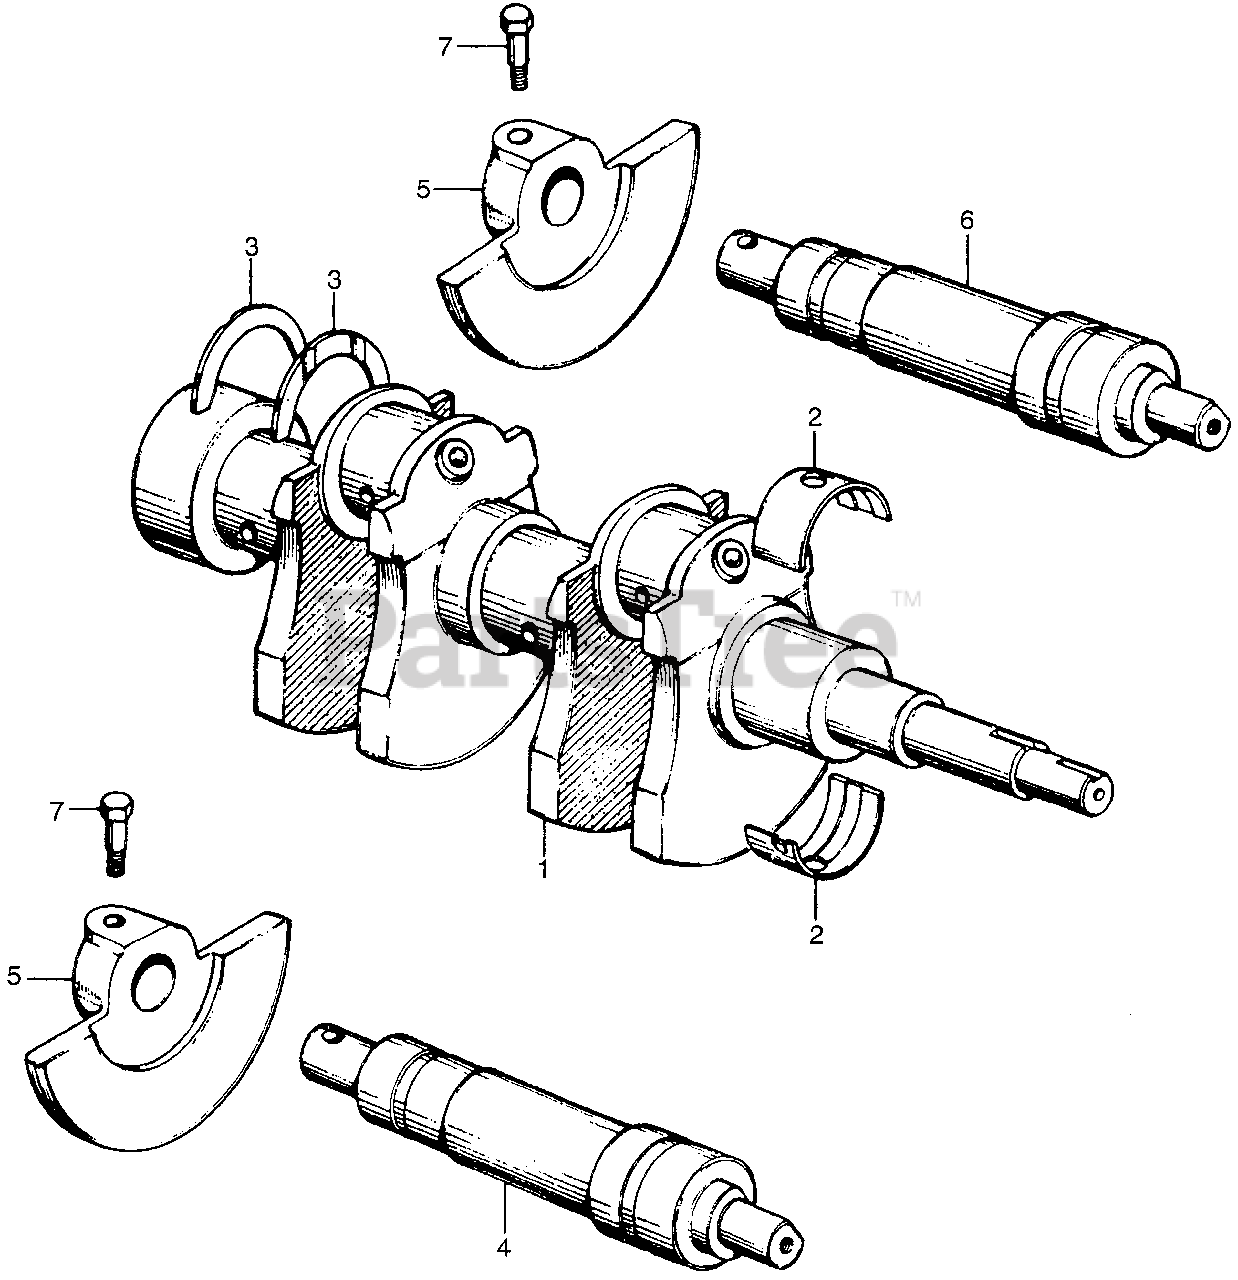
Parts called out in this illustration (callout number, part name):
1	CRANKSHAFT
2	BEARING, MAIN (-0.008/-0.011) (YELLOW)
2	BEARING, MAIN (-0.005/-0.008) (GREEN)
2	BEARING, MAIN (-0.002/-0.005) (BROWN)
2	BEARING, MAIN (-0.004/+0.001) (BLUE)
2	BEARING, MAIN (+0.001/-0.002) (BLACK)
3	WASHER, THRUST
4	SHAFT, FR. BALANCER
5	WEIGHT, BALANCER
6	SHAFT, RR. BALANCER
7	BOLT, BALANCER
